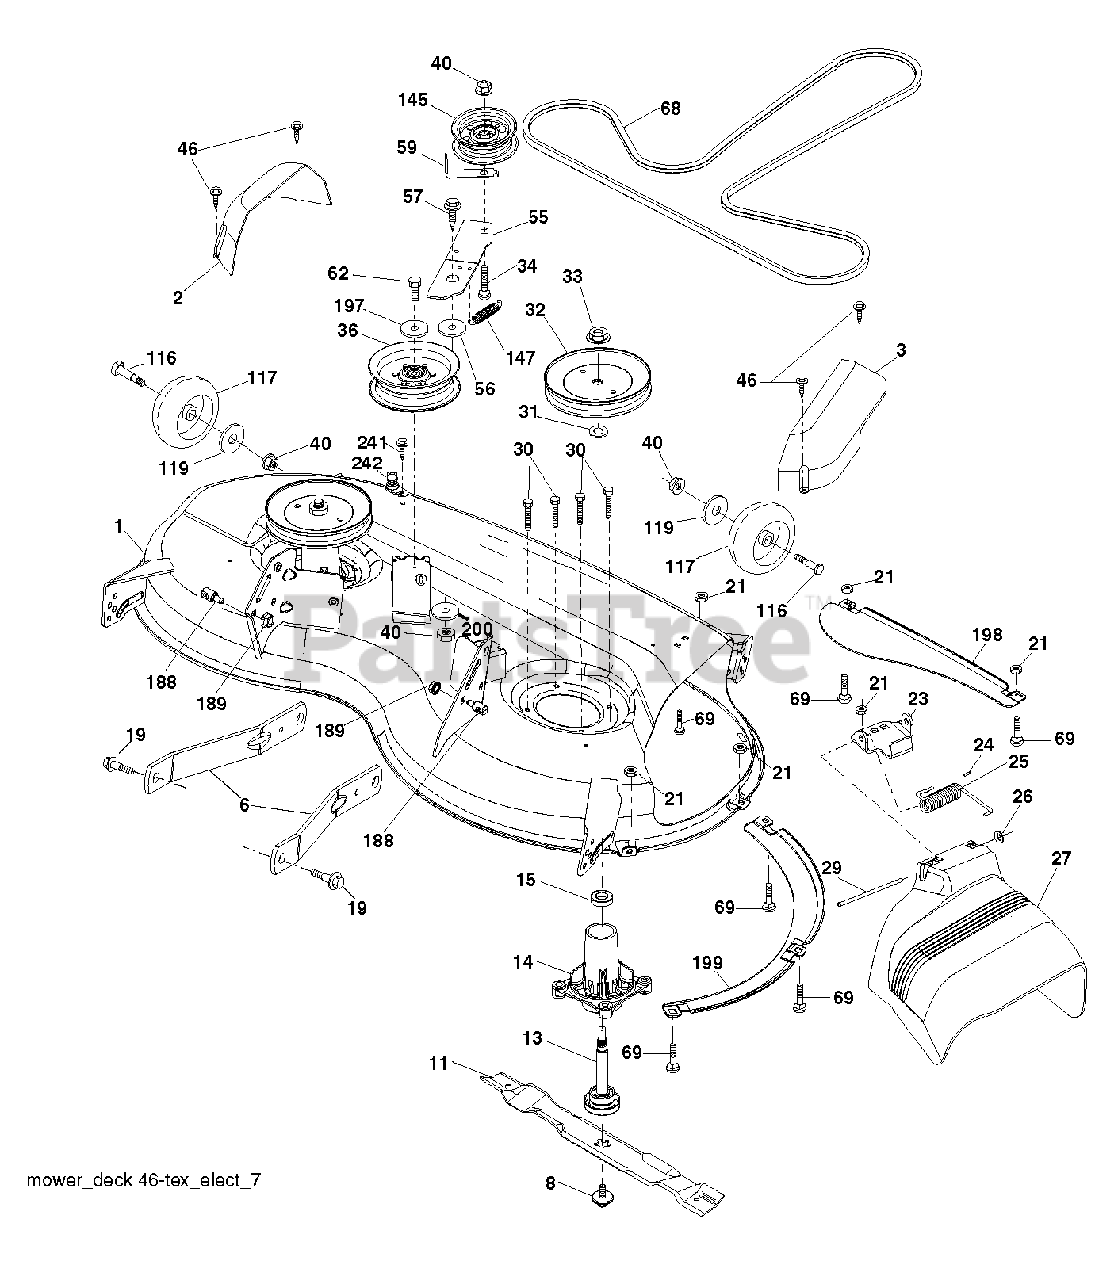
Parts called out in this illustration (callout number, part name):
1	DECK.WLDMT.W/TB.46.4GA.TTR
2	COVER.MANDREL.RH.46"
3	COVER.MANDREL.LH.46"
6	ARM.SUSPENSION.MOWER.R
8	BOLT.WASHER.ASM.7/16-2
11	BLADE.MOWER.46".HI.LIFT
13	SHAFT.ASM.MDRL.N/GREASE.38
14	HOUSING.MANDREL.4PT.
19	BOLT.SHOULDER
21	LOCKNUT
23	BRKT.DEFLECTOR.38"2005+
24	CAP-SLEEVE LT
25	SPRING.TORSION.DEFLECT
26	NUT PUSH M
27	SHIELD.DEFLECTOR.MOWER.46"BLAC
29	ROD.HINGE
30	SCREW, WASHER HEAD
31	WASHER.SPACER.MANDREL
32	PULLEY.MANDREL.5.438.PD
33	NUT.FLANGE.LOCK.TOP
34	BOLT.3/8-16X1.50
36	PULLEY.IDLER.2006
40	NUT LOCK FLG 3/8-16 UNC
46	SCREW.1/4-20X5/8
56	SPACER.RETAINER
57	SCREW 3/8-16X1
59	GUARD, BELT
62	BOLT-HEX EAK
68	V-BELT
69	BOLT
116	BOLT.SHOULDER.3/8-16X3-5/8.
117	WHEEL. GUAGE RALLY
119	WASHER
145	PULLEY.IDLER.48"PRIMARY
147	SPRING.MOWER.DRIVE.ELECTRIC
188	STUD.FASTNER.W/ANTI-ROTATE
189	NUT LOCK HEX FLANGE 5/16-18
197	WASHER
198	BAFFLE CENTER FRONT
199	BAFFLE FRONT RH
200	WASHER.13/32 X 1 X 1/2.11GUARD
241	SCREW.TT.#10-32X.5.3/8.FLANGE
242	PORT.WASHOUT
